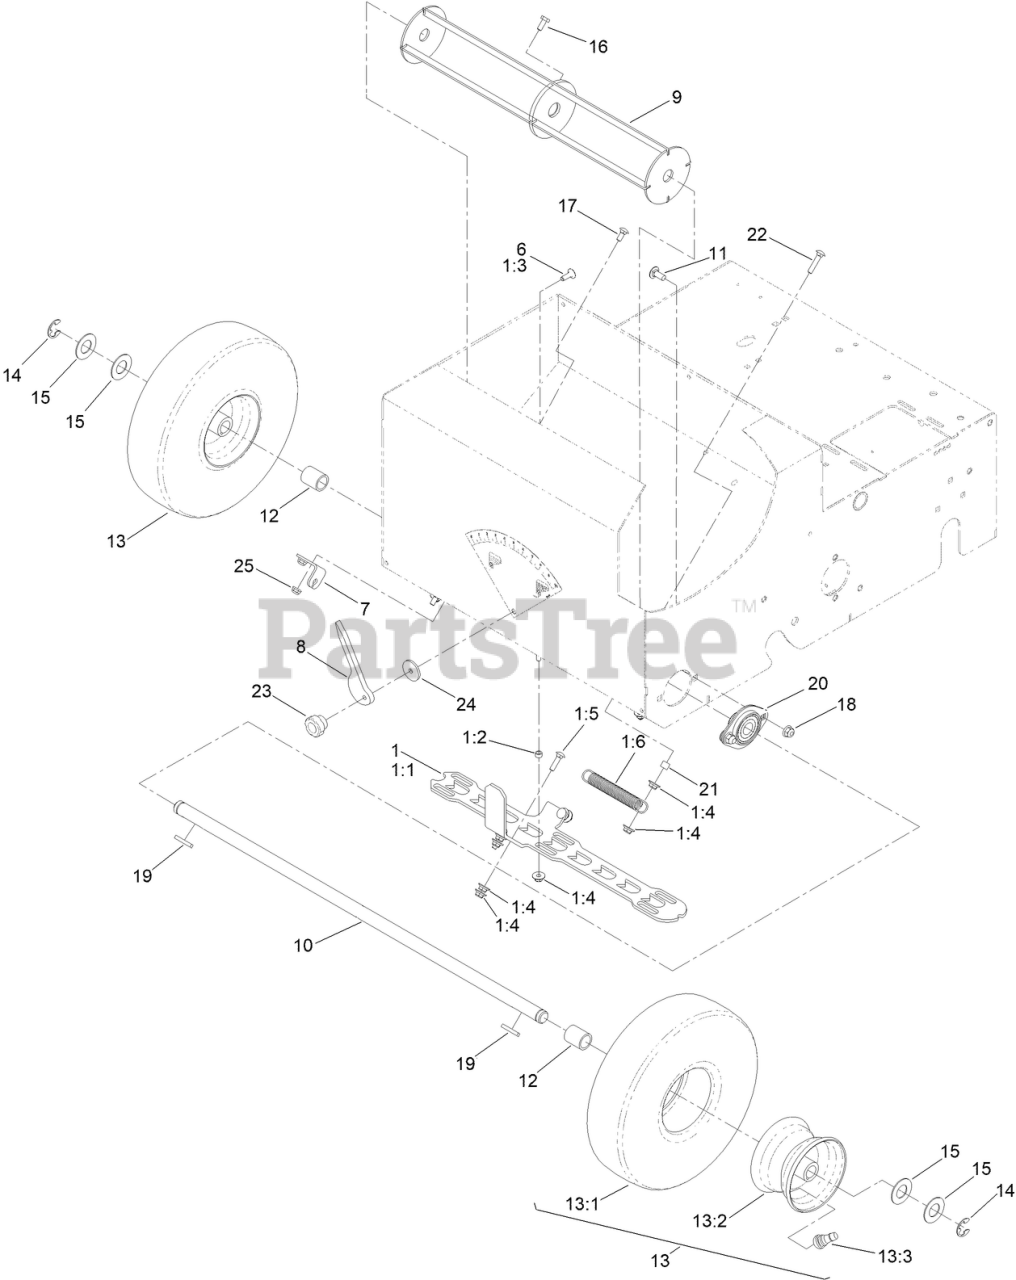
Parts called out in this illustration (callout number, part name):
1	SEED GATE KIT
1:1	GATE-SEED
1:2	SPACER
1:3	BOLT-CARR
1:4	NUT-HF
1:5	SCREW-CARR
1:6	SPRING-EXTENSION
6	BOLT-CARR
7	BRACKET-FLOW, SEED
8	GAUGE-FLOW, SEED
10	AXLE-FRONT
11	SCREW-CARR
12	SPACER
13	WHEEL ASM
13:2	WHEEL-RIM
13:3	VALVE
14	E-RING
15	WASHER-FLAT
16	SCREW-HH
17	SCREW-CARR
18	NUT-HF, NI
19	KEY-SQUARE
20	BEARING
21	SPACER
22	SCREW-CARR
23	KNOB-CHUTE
24	WASHER
25	NUT-HF
